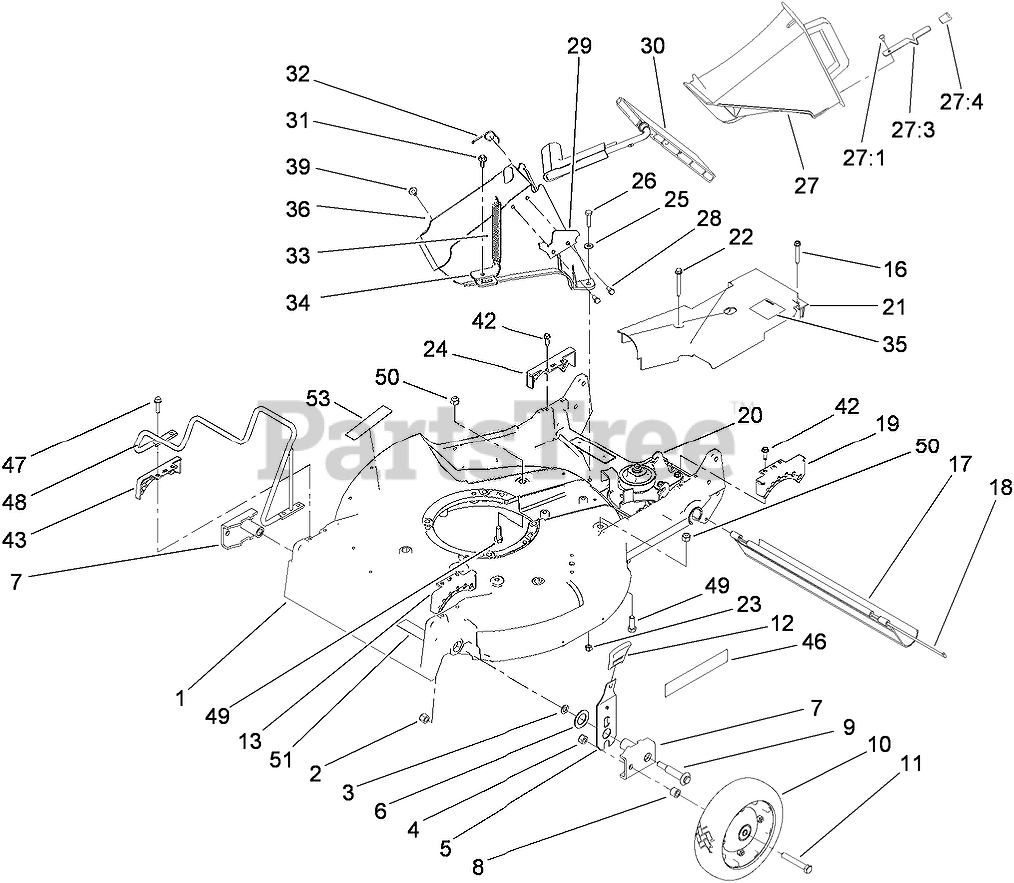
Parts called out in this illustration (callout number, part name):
1	HOUSING ASM
2	NUT-LOCK
3	WASHER
4	NUT-LOCK, CONE
5	FRONT SPRING ARM ASM
6	WASHER-THRUST
7	ARM-PIVOT, FRONT
8	SPACER-WHEEL
9	SCREW-SHOULDER
10	Wheel and Tire ASM
11	SCREW-HH
12	KNOB-HOC
13	QUADRANT-FRONT, LH
16	SCREW-HWHTF
17	SHIELD-TRAILING
18	ROD-SHIELD
19	QUADRANT-REAR, LH
20	GEAR CASE ASM
21	COVER-BELT
22	SCREW-HHFTF
23	NUT-LOCK, NI
24	QUADRANT-REAR, RH
25	WASHER-FLAT
26	SCREW-HH
27	DISCHARGE PLUG ASM
27:1	RIVET-HEAD, FLAT
27:3	LATCH-PLUG, DISCHARGE
27:4	GRIP-LATCH
28	SCREW-PLASTITE
29	LATCH-PLATE
30	DISCHARGE DOOR ASM
31	SCREW-HWH
32	RETAINER-DOOR
33	SPRING-DOOR
34	BRACKET-SPRING
35	LABEL-GREASE
36	TUNNEL-DISCHARGE
39	SCREW AND WASHER ASM
42	SCREW-HWHTF
43	QUADRANT-FRONT, RH
47	SCREW-HWHTF
48	GUARD-ENGINE
49	SCREW-HH
50	NUT-LOCK, NI
51	DECAL-BLADE
53	DECAL-ARRESTER, SPARK
